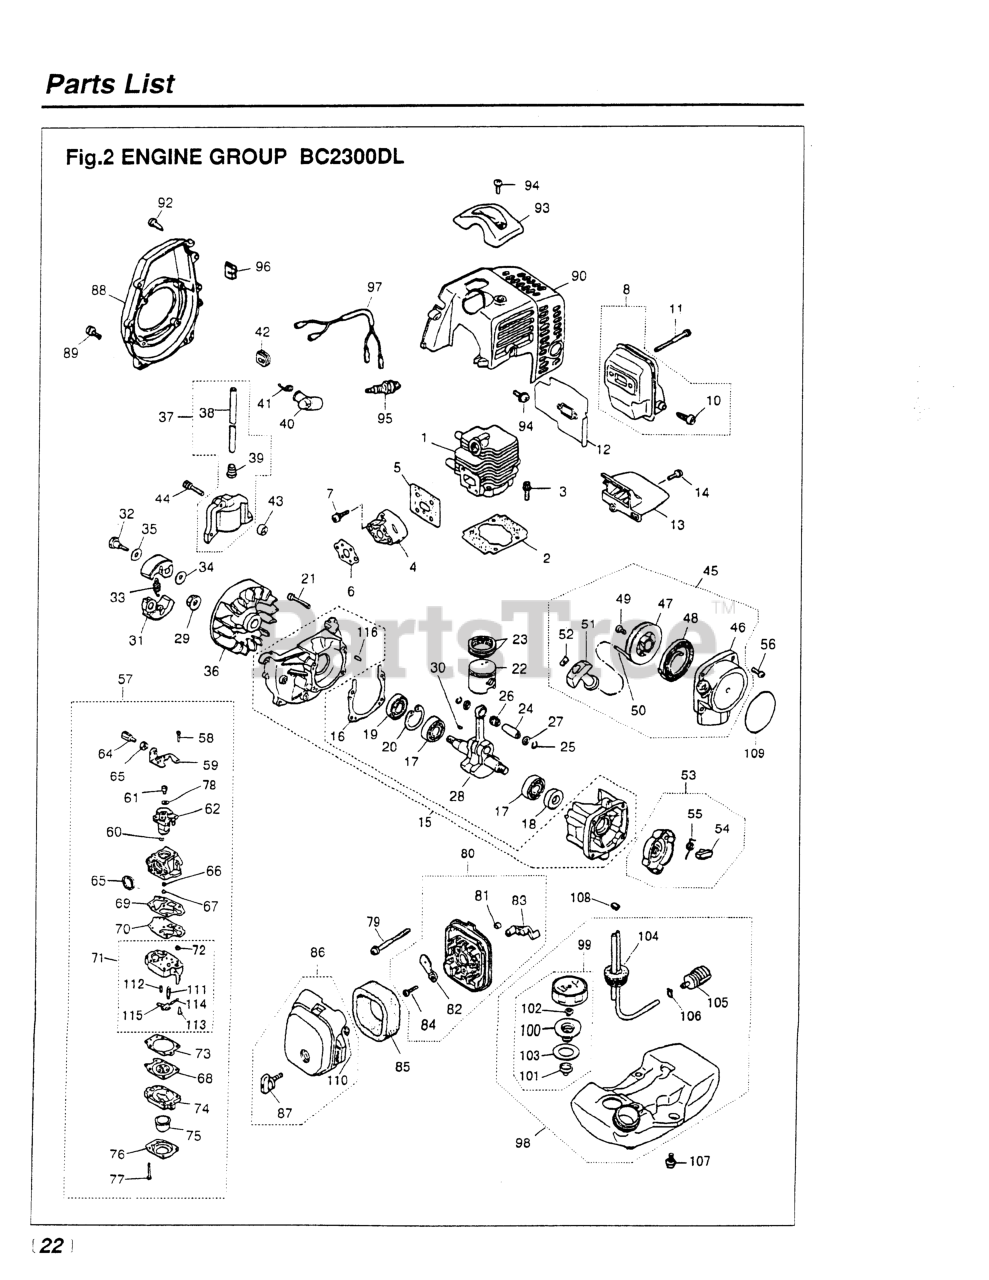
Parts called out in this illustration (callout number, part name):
1	CYLINDER
3	BOLT, M5 X 22
5	GASKET (RPLS -13120)
6	GASKET (REPLACES -13130)
7	SCREW, M5X20 (RPLS.1400-75510)
8	MUFFLER ASSY (RPLS 5501- )
10	ARRESTER (RPLS 5850-15140)
11	BOLT, M5 x 50
12	GASKET, MUFFLER (RPLS -15111)
14	SCREW, M4 X 16
15	CRANKCASE
16	GASKET (RPLS -21140)
17	BEARING
18	SEAL, OIL (RPLS 1100-21210)
19	SEAL, OIL (RPLS 1140-21220)
20	RING, SNAP, M28 x 1.2
21	BOLT, M5 X 30
22	PISTON (REPLACES 1140-41110)
23	RING, PISTON (RPLS 1850-41210)
24	PIN, PISTON 5x8x26
25	RING, SNAP (RPLS 1101-41320)
27	WASHER
28	CRANKSHAFT (RPLS 1850-42000)
30	KEY
31	SHOE (RPLS 1100-51114)
32	BOLT
33	SPRING, CLUTCH (RPLS-51220)
34	WASHER, FLAT (USE 182303)
36	ROTOR
37	COIL ASSY (RPLS 5500-71200)
38	CORD
39	CAP
41	SPRING
42	GROMMET
43	SPACER (RPLS -71260)
44	BOLT
45	RECOIL ASSEMBLY
46	CASE
47	REEL
48	SPRING, SPIRAL
49	SCREW (RPLS -75150)
51	KNOB
52	PLATE, STOPPER
53	PULLEY ASSY (RPLS -75210)
54	RATCHET (RPLS 1850-75220)
55	SPRING, RETURN
56	SCREW, M4 X 16
57	CARBURETOR
58	SCREW
60	RING
61	SWIVEL
62	VALVE ASSY
63	SCREW, CABLE ADJUSTER
64	NUT, CABLE ADJUSTER
65	RING, PACKING
66	RING, O
67	JET
68	DIAPHRAGM (USE 4810-81260)
69	GASKET, PUMP
70	DIAPHRAGM
71	BODY, PUMP
73	GASKET, DIAPHRAGM
74	BODY, PURGE
75	PUMP, PRIMING
76	COVER, PUMP
77	SCREW
78	WASHER
79	SCREW, M5 x 60
80	BODY-A (RPLS -82101)
81	SLEEVE
82	PLATE, CHOKE (RPLS-82130)
83	LEVER, CHOKE
84	SCREW (REPLACES 50030272)
85	ELEMENT
87	KNOB (RPLS -82220)
88	COVER, FAN (RPLS-31110)
89	SCREW, M5X20 (RPLS.1400-75510)
90	COVER, ENGINE (RPLS -32111)
91	SCREW, M5 x 12
92	SCREW, HOUSING
93	GUARD, PLUG
94	SCREW,M5 X 14 (RPLS 1400-15510
97	CORD COMP (RPLS -73200)
101	HOLDER, CAP
102	VALVE (NLA WHEN OUT)
103	PACKING
104	PIPE COMPLETE
105	FILTER (RPLS 1850-85300)
106	CLIP (REPLACES 2841-31280)
107	SCREW
108	CLIP
109	LABEL, RECOIL (RPLS -91121)
110	RING
111	VALVE, INLET
112	SPRING, METERING LEVER
113	SCREW, METERING LEVER PIN
114	PIN, METERING LEVER
115	LEVER
116	PIN
